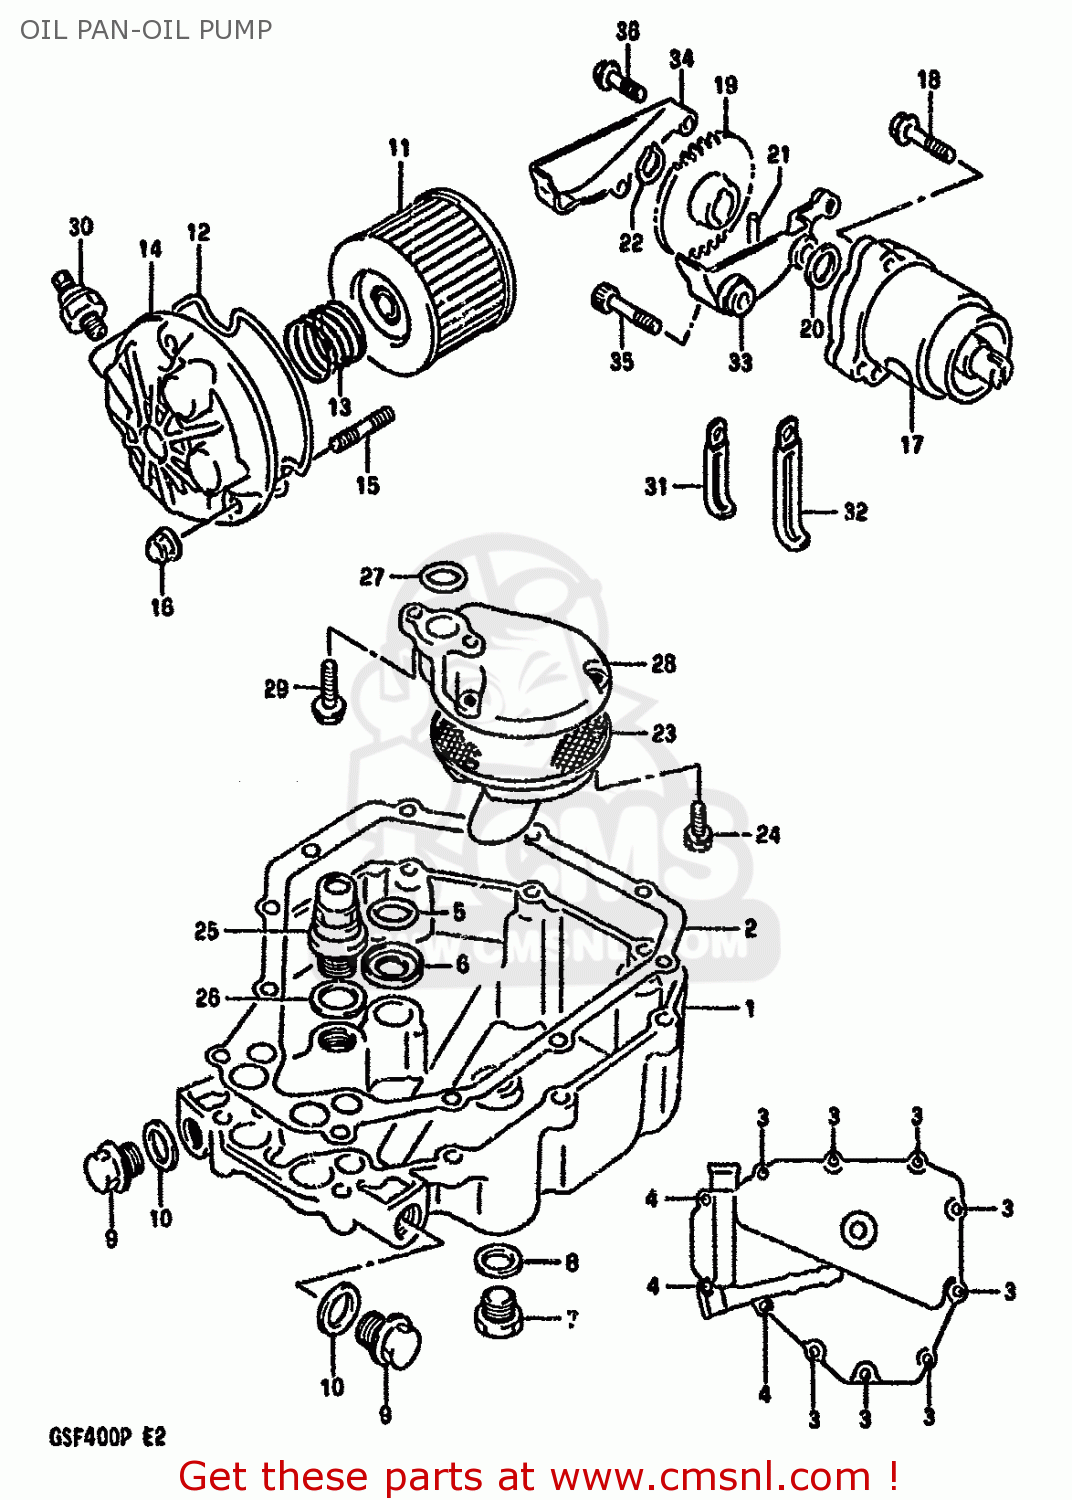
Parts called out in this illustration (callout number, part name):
1	PAN,OIL
2	GASKET,OIL PAN (NAS)
3	BOLT 6X25
4	BOLT 6X30
5	O RING(D:3.2,ID:15.8)
6	GASKET,OIL OUTLET (NAS)
7	PLUG
8	GASKET(14X19.2X2) (NAS)
9	PLUG(14X12)
10	GASKET(14X19.2X2) (NAS)
11	FILTER ASSY,ENGINE OIL
12	O RING,OIL FILTER CHAMBER CAP
13	SPRING
14	CAP,FILTER
15	STUD 6X20
16	NUT 6MM
17	PUMP ASSY,ENGINE OIL
18	BOLT
19	GEAR,OIL PUMP DRIVEN
20	SHIM
21	PIN(5X18)
22	CIRCLIP,12 MM
23	STRAINER,ENGINE OIL
24	BOLT
25	VALVE ASSY,OIL RELIEF
26	GASKET(16X22X2) (NAS)
27	O RING(D:3.2,ID:15.8)
28	PROTECTOR,OIL STRAINER
29	BOLT 6X20
30	SWITCH ASSEMBLY,OIL PRESSURE
31	CLAMP
32	CLAMP
33	CASE,OIL SEPARATOR
34	CAP,OIL SEPARATOR
35	BOLT
36	BOLT
